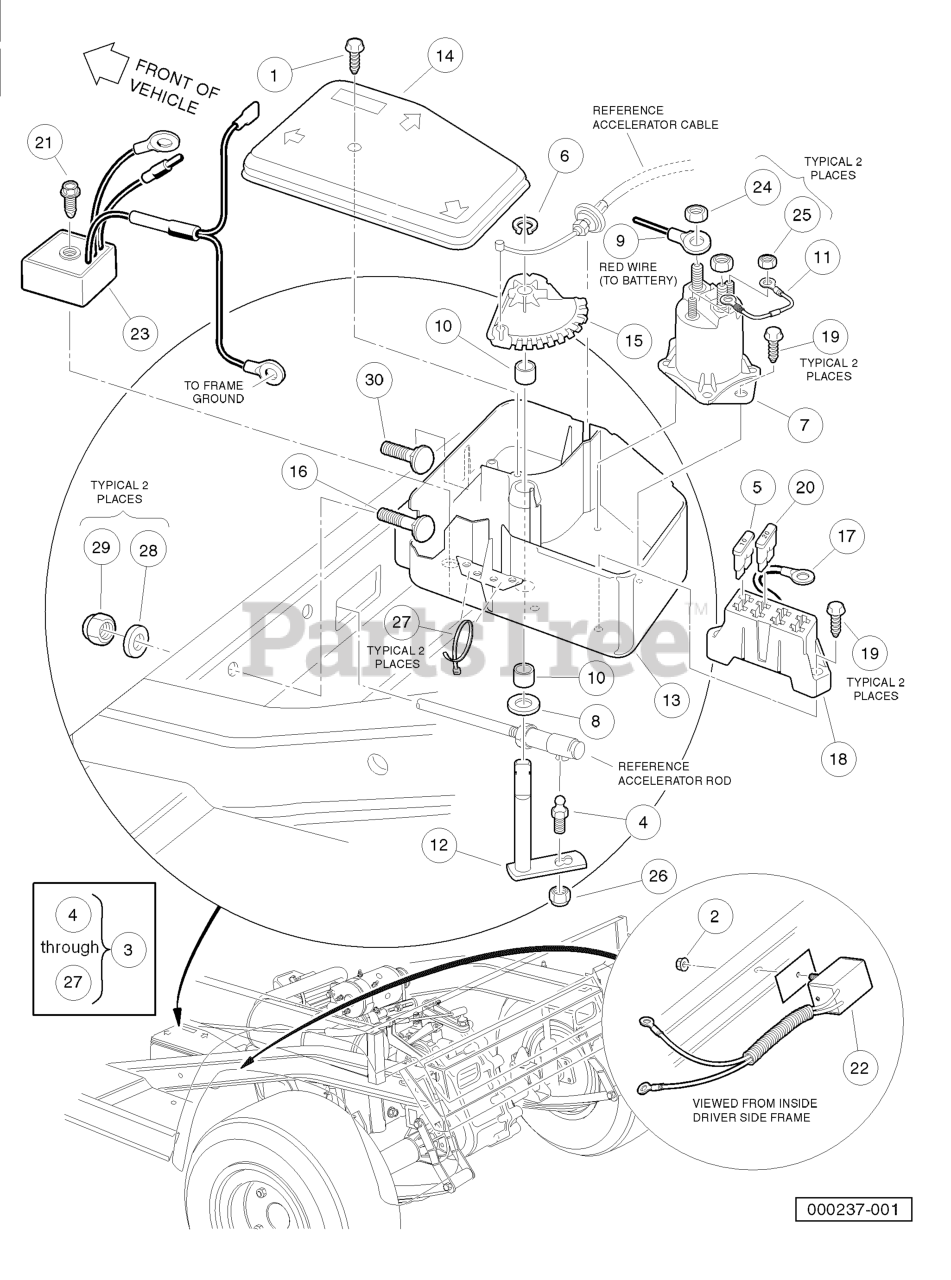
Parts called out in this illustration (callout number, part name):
1	SCREW, #12-16 X .625 HI-LO
2	LOCKNUT, 5/16-18 HEX FLANGE
3	Assembly, Electrical Component Box
5	10 AMP FUSE
7	SOLENOID, 12 VOLT
9	WIRE ASSY #6 RED
10	BUSHING, SECONDARY WGHT SPLIT
11	ASM, DIODE
12	BELL CRANK AND SHAFT ASSY
13	BOX, ELECTRICAL COMPONENT
14	COVER, OHV ELECTRIC BOX
15	CAM, ELECTRIC BOX
16	BOLT,5/16-18 X 2.0 RD HD SQ NK
17	WIRE ASSY, #10 RED
18	FUSE BLOCK
19	SCREW, #12-16 X .625 HI-LO
20	FUSE - 20 AMP
21	SCREW, 1/4-15 X .50 HI-LO HEX
22	DIODE ASSY
23	ASM, VOLTAGE REGULATOR
24	NUT, 5/16-18 HEX
25	NUT, #10-32 HEX
26	LOCKNUT, 1/4-28 NYLON INSERT
27	TIE WRAP, 8" NYLON
28	WASHER, 5/16 TYPE A FLAT
29	LOCKNUT, 5/16-18 NYLON INSERT
30	BOLT 5/16-18 X 1.5
